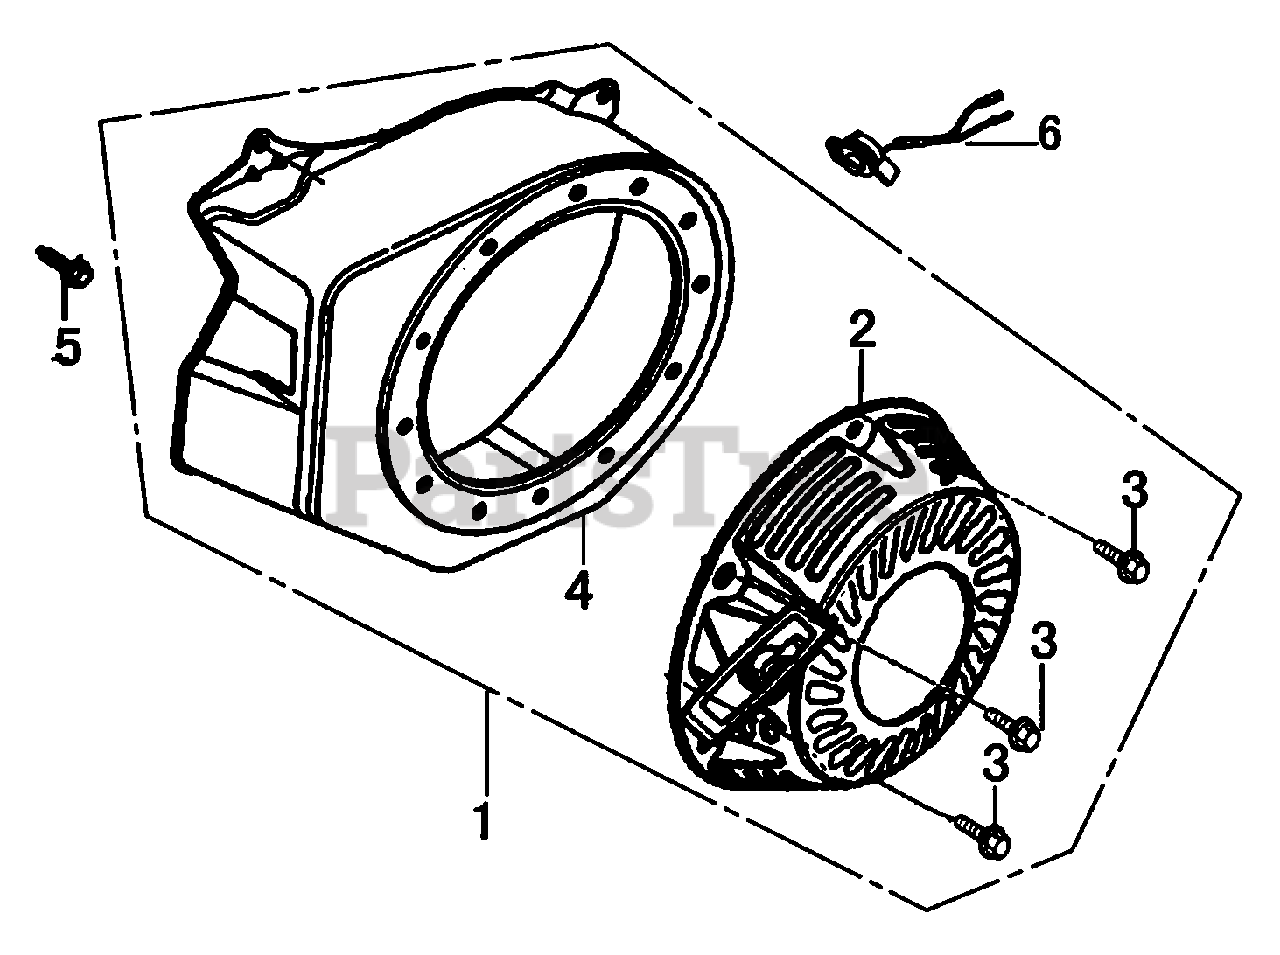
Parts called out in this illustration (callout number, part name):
1	RECOIL STARTER COMP.
2	STARTER ASSY.
3	BOLT, FLANGE
4	COVER COMP., FAN
5	BOLT, FLANGE
6	SWITCH ASSY., ENGINE STOP
